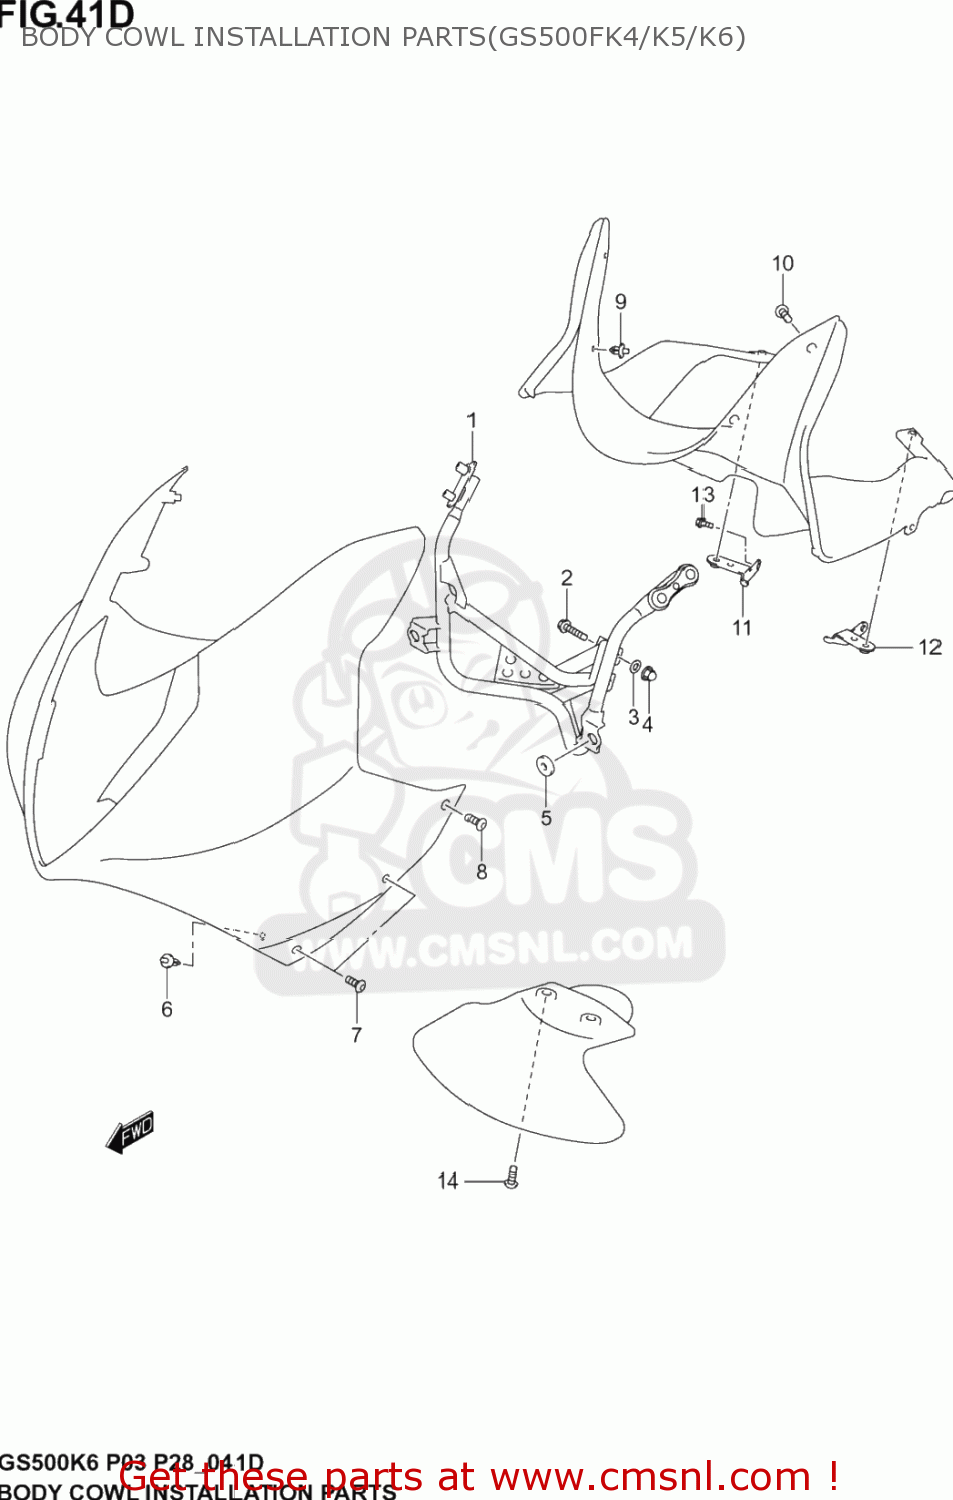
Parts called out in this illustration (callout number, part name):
1	BRACE, COWLING
2	BOLT
3	WASHER
4	NUT
5	CUSHION
6	CLIP(BLACK)
7	SCREW(5X13)
8	SCREW(5X16)
9	CLIP(BLACK)
10	SCREW(5X16)
11	BRACKET, UPPER RH
12	BRACKET,UPPER
13	BOLT OIL LEVEL
14	BOLT
